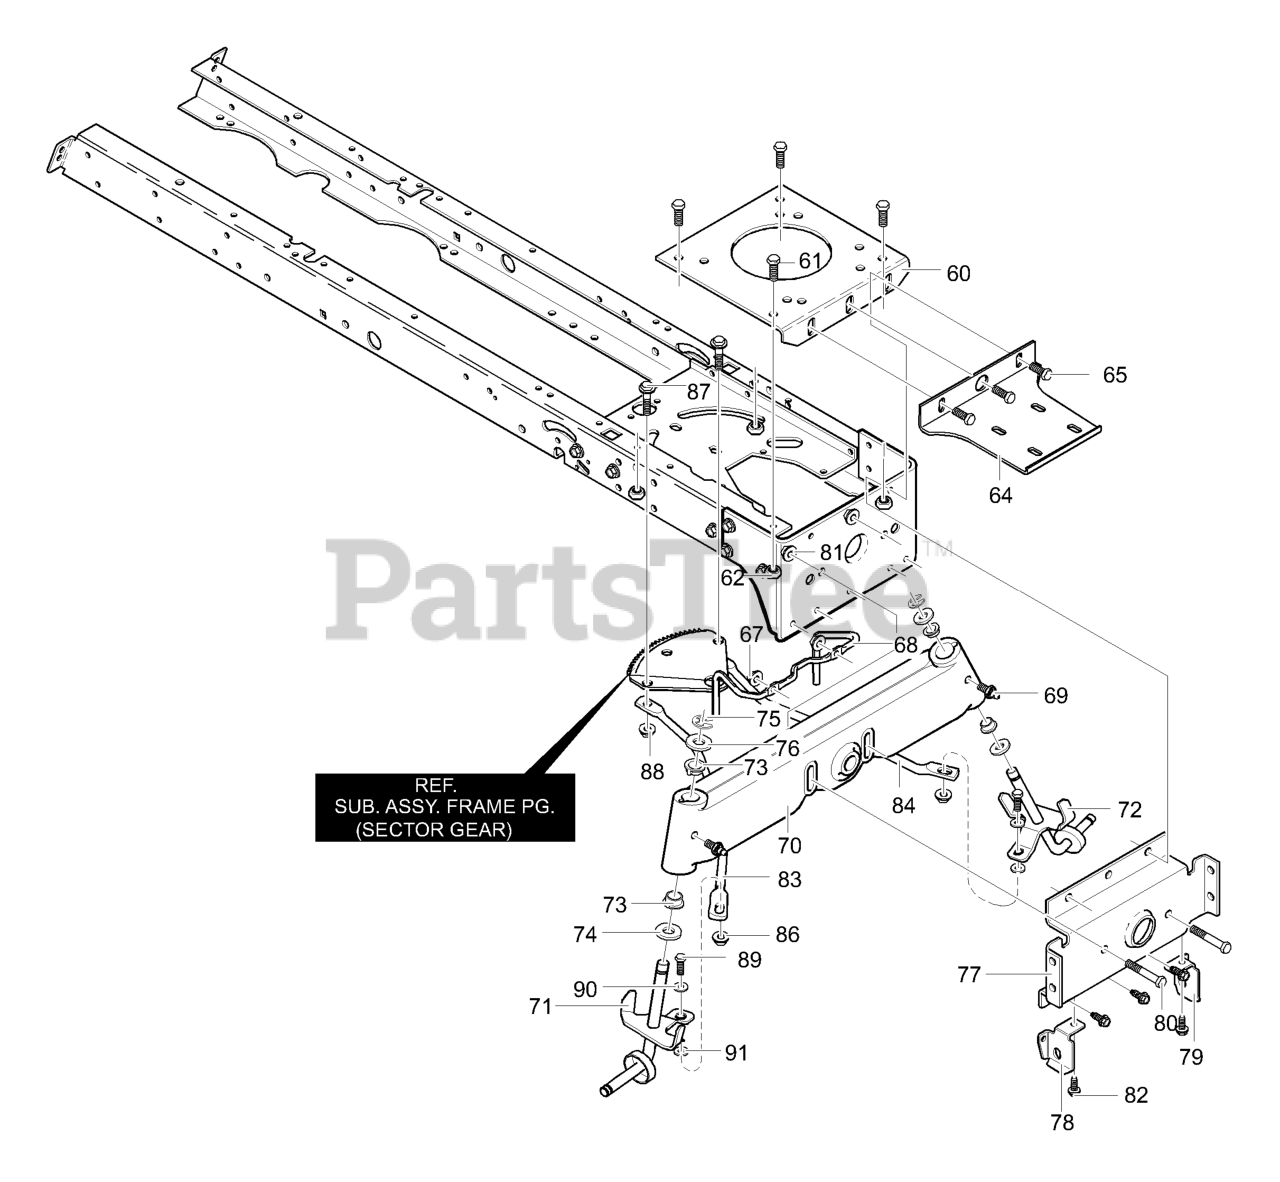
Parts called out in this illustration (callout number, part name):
60	Engine Plate
61	SCREW, .312-18x.75
62	NUT, 5/16-18
64	BRACKET, Muffler Mount
65	SCREW, .312-18x.75
67	NUT, 5/16-18
68	GUIDE-Stack Pulley Belt
69	Zerk, Grease
70	Axle, Cast Machined
71	Spindle, Long RH
72	Spindle, Long LH
73	BEARING, Spindle
74	WASHER, .766IDx1.62ID
76	WASHER, Flat
77	HANGER, Axle
78	HANGER, Deck RH
79	HANGER, Deck LH
80	SCREW, 5/16-18 x 3.00
81	NUT, 5/16-18
82	SCREW, .312-18x.75
83	Drag Link, LH
84	Drag Link, RH
86	NUT, 3/8-16
87	BOLT, Shoulder
88	NUT, 3/8-16
89	SCREW, 3/8-16 x 1.50
90	FLATWASHER
91	FLATWASHER
